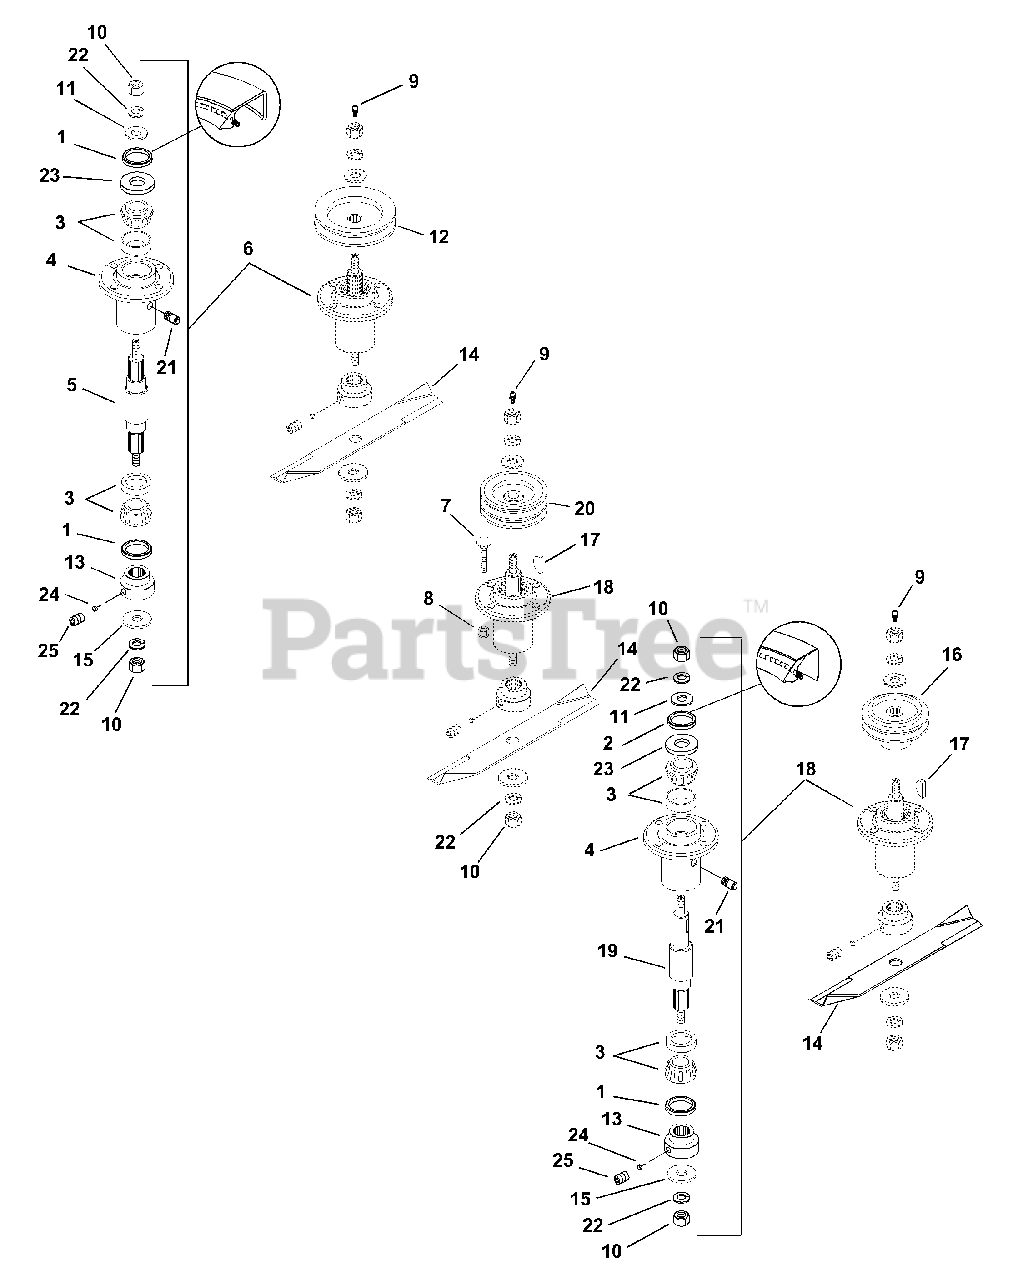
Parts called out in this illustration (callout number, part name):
1	Seal 1.987 x 1.375 x .313
2	Seal 1.987 x 1.500 x .313
3	Assembly, Bearing Cup & Cone
4	Bearing Housing
5	Spindle Shaft
6	Service Kit Spindle Assembly
7	Bolt-Round Head Square Neck .38-16 x 1.50
8	Nut-Locking-Nyl .38-16
9	Fitting-Lube .125
10	Nut-Hex .625-11 Grade 2
11	Washer-Flat-Steel .687 x 1.312 x .150
12	Sheave 60" Mower
12	Sheave 50" Mower
14	Blade, 60" Mower
14	Blade, 50" Mower
15	Washer-Flat .640 x 1.81 x .250
16	Sheave 60" Mower
16	Sheave 50" Mower
17	Key-Woodruff .25 x .88
18	Service Kit Spindle Assembly
19	Spindle Shaft
20	Sheave 60" Mower
20	Sheave 50" Mower
21	Relief Fitting Grease
22	Washer-Locking .625 x .156
23	Washer-Flat-Steel 1.007 x 1.542 x .062
25	Screw-Set .25-20 x .25
